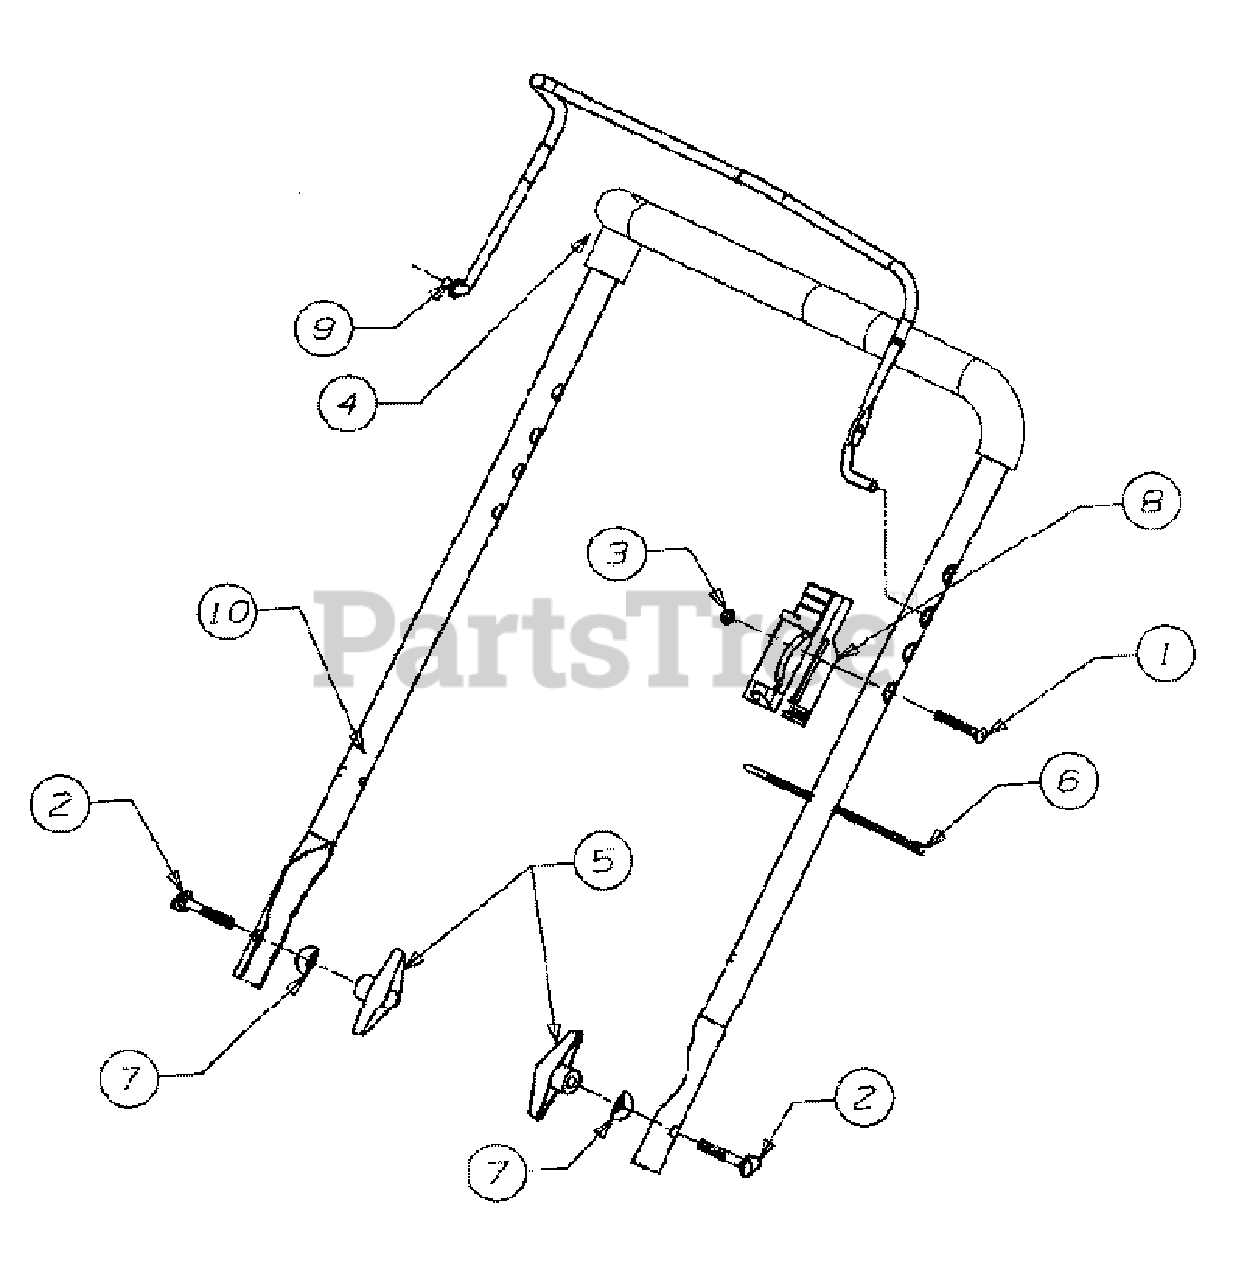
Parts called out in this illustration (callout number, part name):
1	Screw-Oval C-Sink L
2	Bolt-Carriage
3	Nut Insul. Lock
4	Grip Foam
5	Knob Handle
6	Tie Cable
7	Washer Saddle
8	Body-Lever Control
